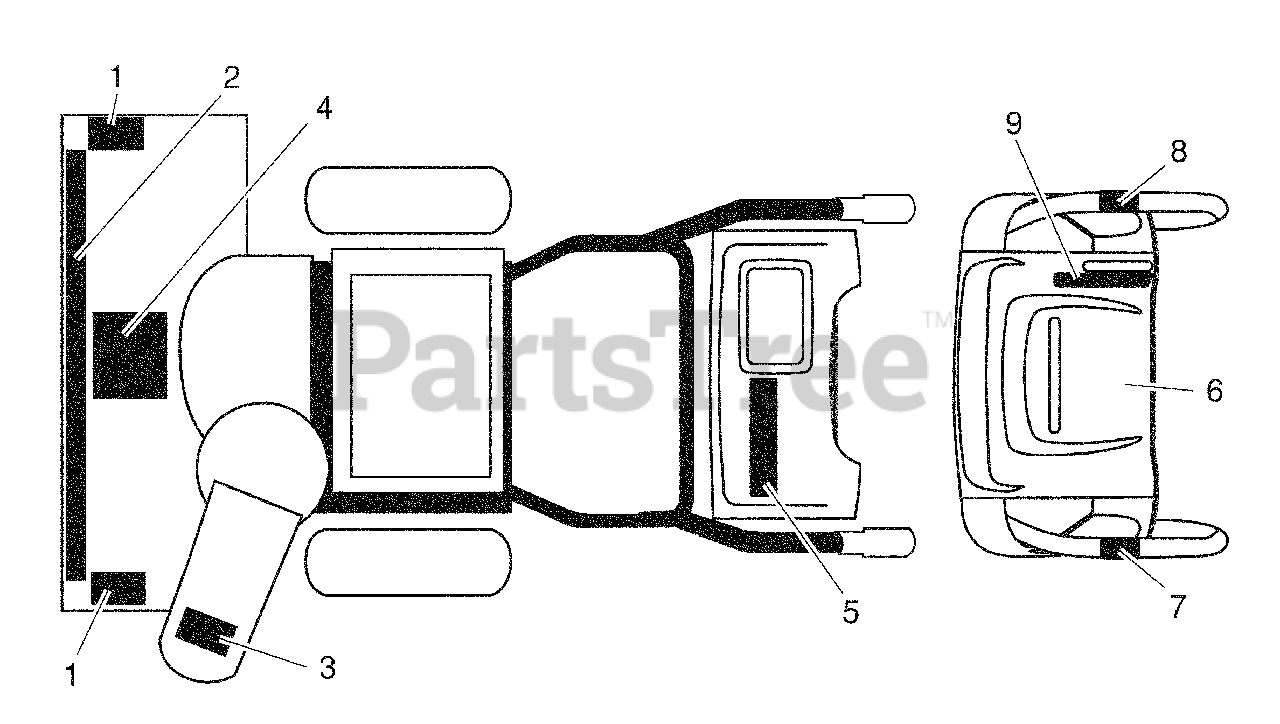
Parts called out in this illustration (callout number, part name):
1	DECAL, DANGER
2	DECAL, HUSQVARNA
3	DECAL, DANGER, DEFLECTOR
4	DECAL, DANGER
5	DECAL, HUSQVARNA, 924SBb
6	DECAL, INSTRUCTION
7	DECAL, TRACTION LEVER
8	DECAL, AUGER LEVER
9	DECAL, SPEED CONTROL
